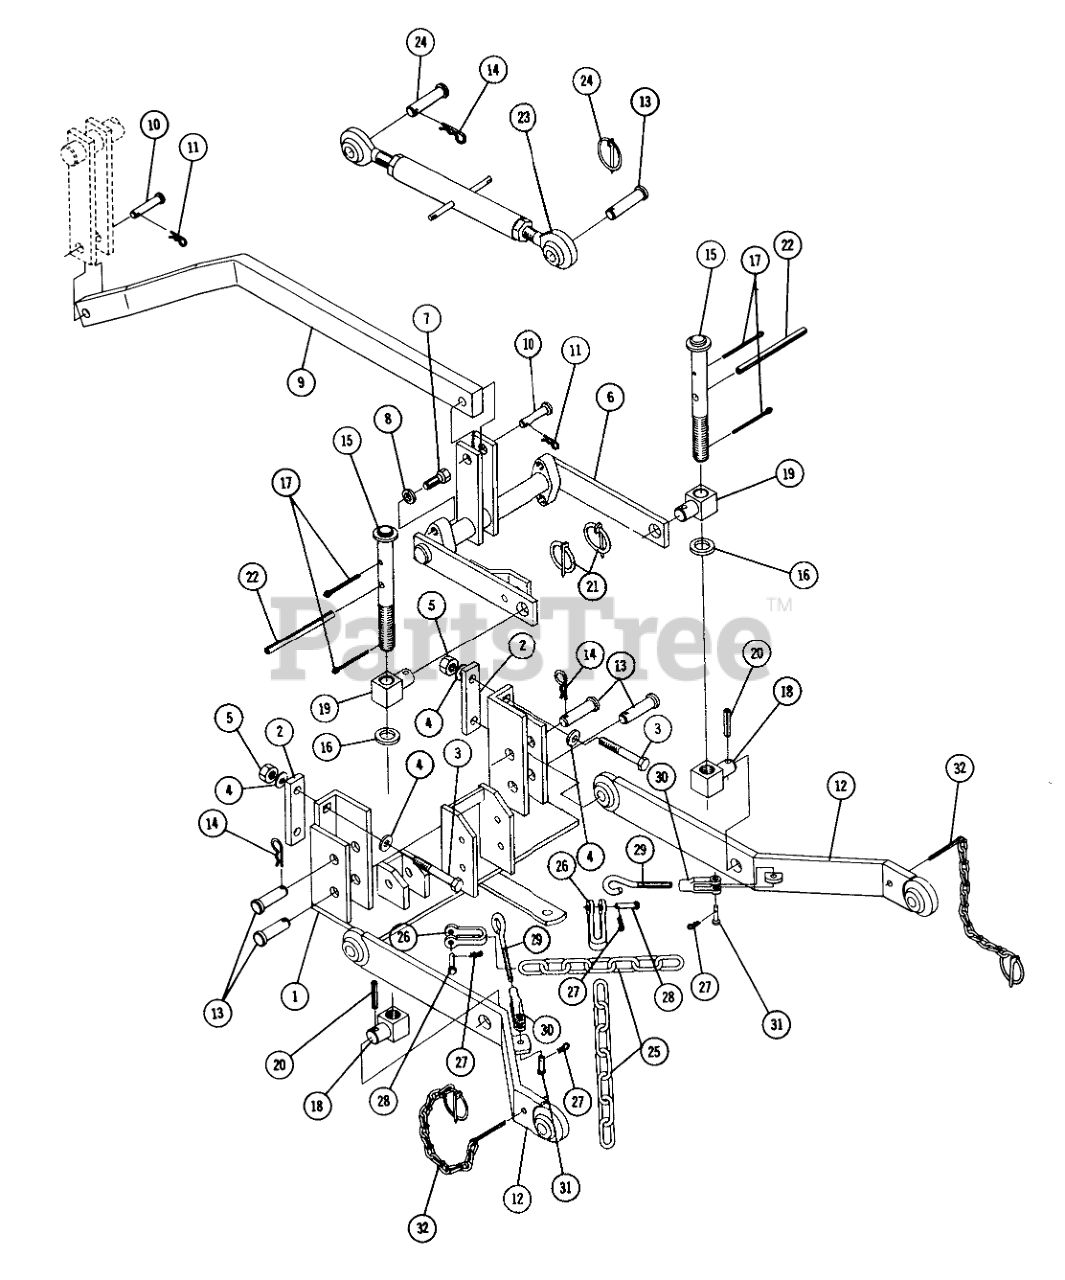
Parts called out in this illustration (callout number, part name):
1	Mounting Frame
2	BRACKET-REAR LINK MOUNTING
3	Bolt Hex 3/8-16 x 1
4	Washer
5	3/8-16 E.S.
6	Hitch Lift
7	Bolt 3/8-16 x 1
8	Lockwasher
9	Bar-Hitch Connecting
10	Pin 1/2 Dia.
11	Hairpin
12	Lower Hitch Link
13	PIN 5/8 DIA LINK ATT
14	Hairpen
15	Lift Rod
16	WASHER
17	Cotter Pin 5/32 x 1 1/4
18	Pivot-Tapped
19	Pivot-Plain
20	ROLL PIN 1/4 X 1-1/4
21	HITCH PIN ASSY
23	Link-Upper
24	PIN HITCH UPPER LINK
25	Chain
26	Clevis
27	Hairpin
28	Clevis Pin
29	Hook-Chain
30	CLEVIS
32	Klik Pin
